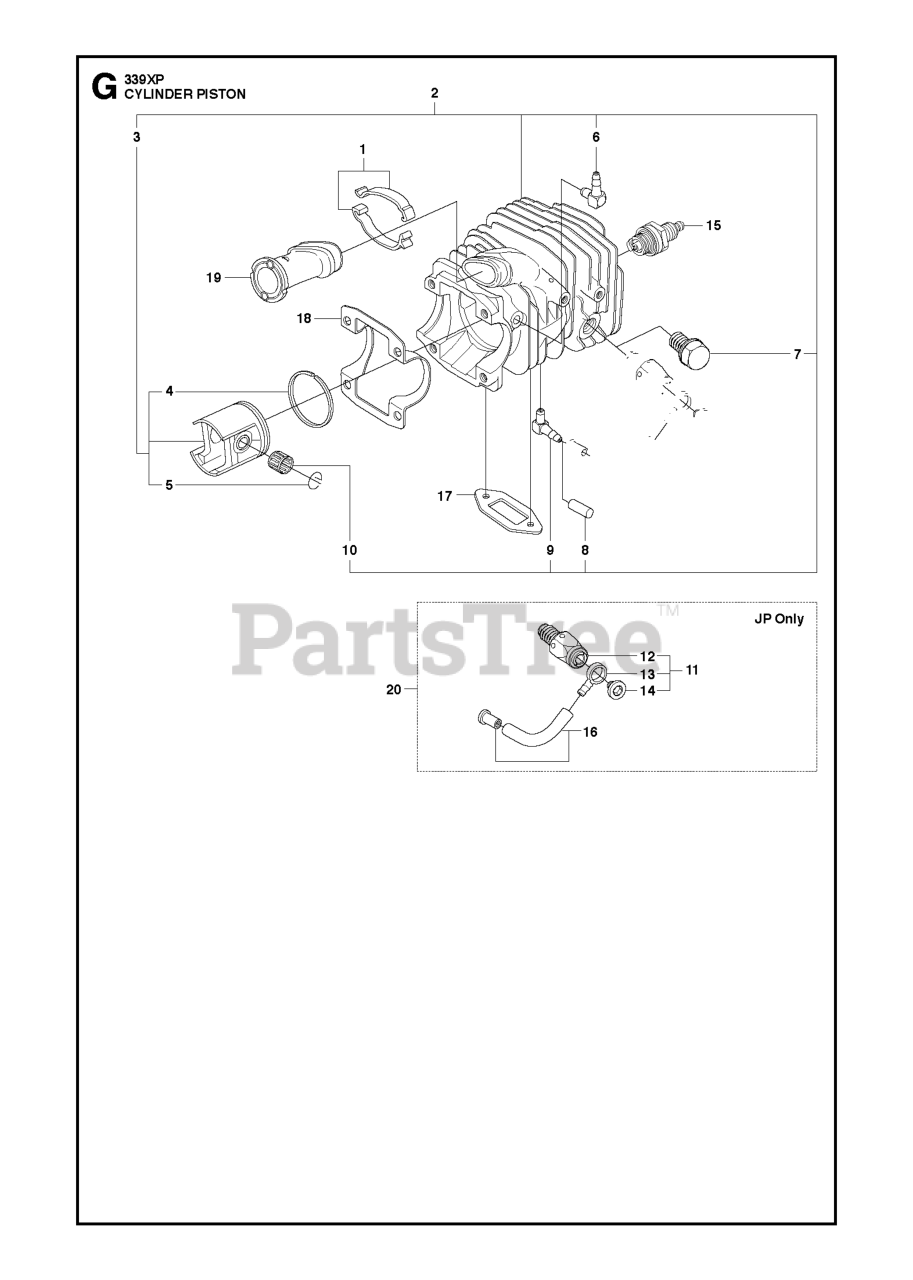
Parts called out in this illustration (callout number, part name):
4	RING
5	LOCKING RING
7	CYLINDER PLUG
8	PROTECTIVE CAP
10	SUPPORT BUSHING
11	VALVE DECOMPR
12	DECOMPRESSION VALVE
15	SPARK PLUG RCJ7Y
16	HOSE ASSY
20	VALVE DECOMPR
